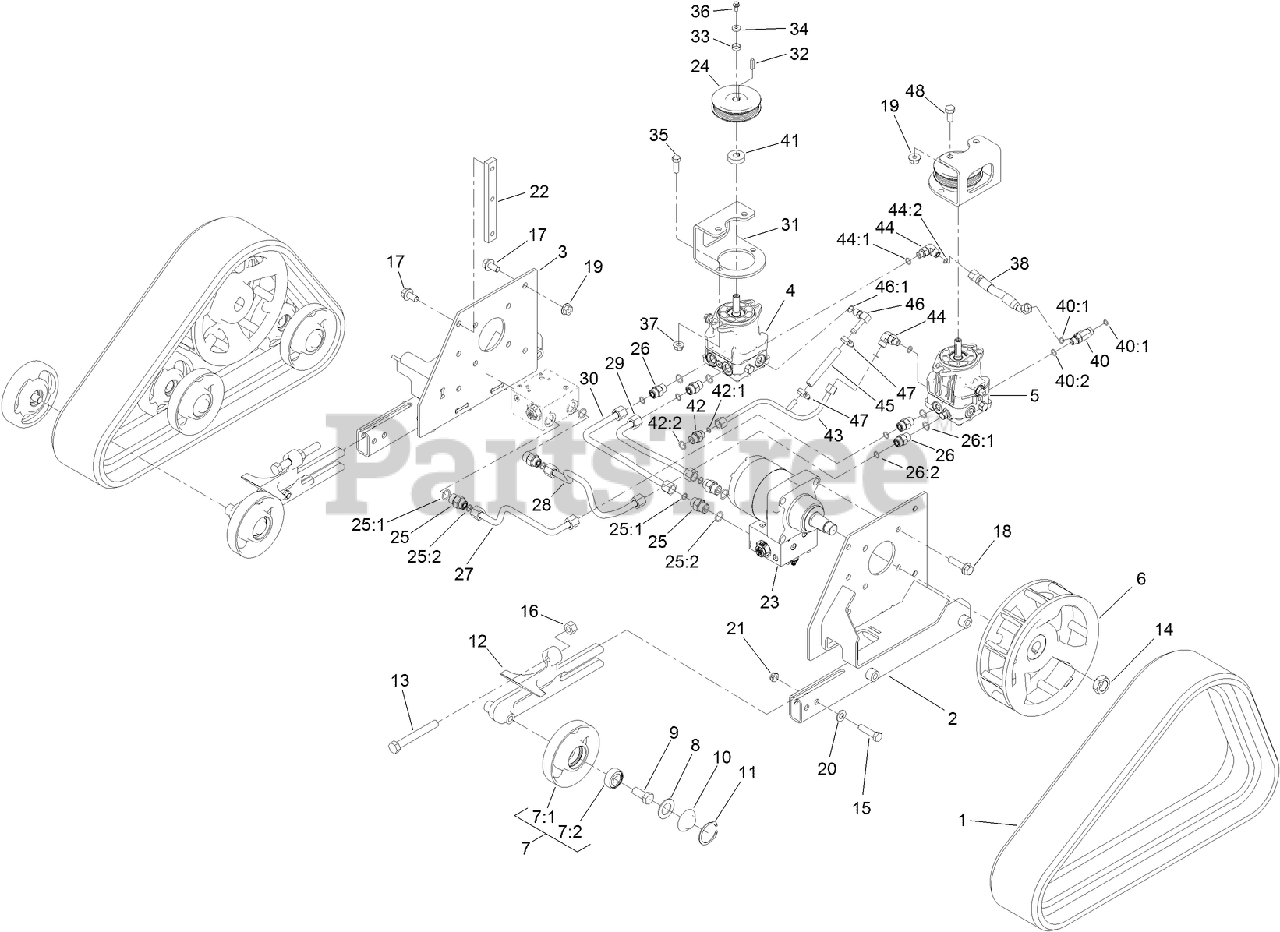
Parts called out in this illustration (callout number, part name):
1	TRACK-RUBBER
2	FRAME-TRACK, LH
3	FRAME-TRACK, RH
4	RH HYD PUMP ASM
5	LH HYD PUMP ASM
6	WHEEL-DRIVE
7	WHEEL-TENSIONER
7:1	WHEEL-TRACK
7:2	BEARING-BALL
8	Gasket-Bogie
9	SCREW-HH
10	CAP-WHEEL, BEARING
11	RING-SNAP, INTERNAL
12	TENSIONER-TRACK
13	SCREW-HH, TAP
14	NUT-LOCK
15	SCREW-HH
16	NUT-HEX
17	SCREW-HHF
18	SCREW-HHF
19	NUT-HHF
20	WASHER-FLAT
21	NUT-LOCK, NI
22	BAR-THREAD
23	HYD MOTOR ASM
24	SHEAVE
25	FITTING-STRAIGHT
25:1	O-RING
25:2	O-RING
26	FITTING-STRAIGHT
26:1	O-RING
26:2	O-RING
27	TUBE-HYD
28	TUBE-HYD
29	TUBE-HYD
30	TUBE-HYD
31	BRACKET-MOUNT, PUMP
32	KEY-PUMP
33	BUSHING
34	WASHER
35	SCREW-HH
36	SCREW-HHF
37	NUT-HF
38	HOSE-HYD
40	FITTING-TEE
40:1	O-RING
40:2	O-RING
41	SPACER
42	FITTING-STRAIGHT
42:1	O-RING
42:2	O-RING
43	TUBE-HYD
44	FITTING-ELBOW, 90 DEG
44:1	O-RING
44:2	O-RING
46	FITTING-ELBOW, 90
46:1	O-RING
47	CLAMP-HOSE
48	SCREW-HH
